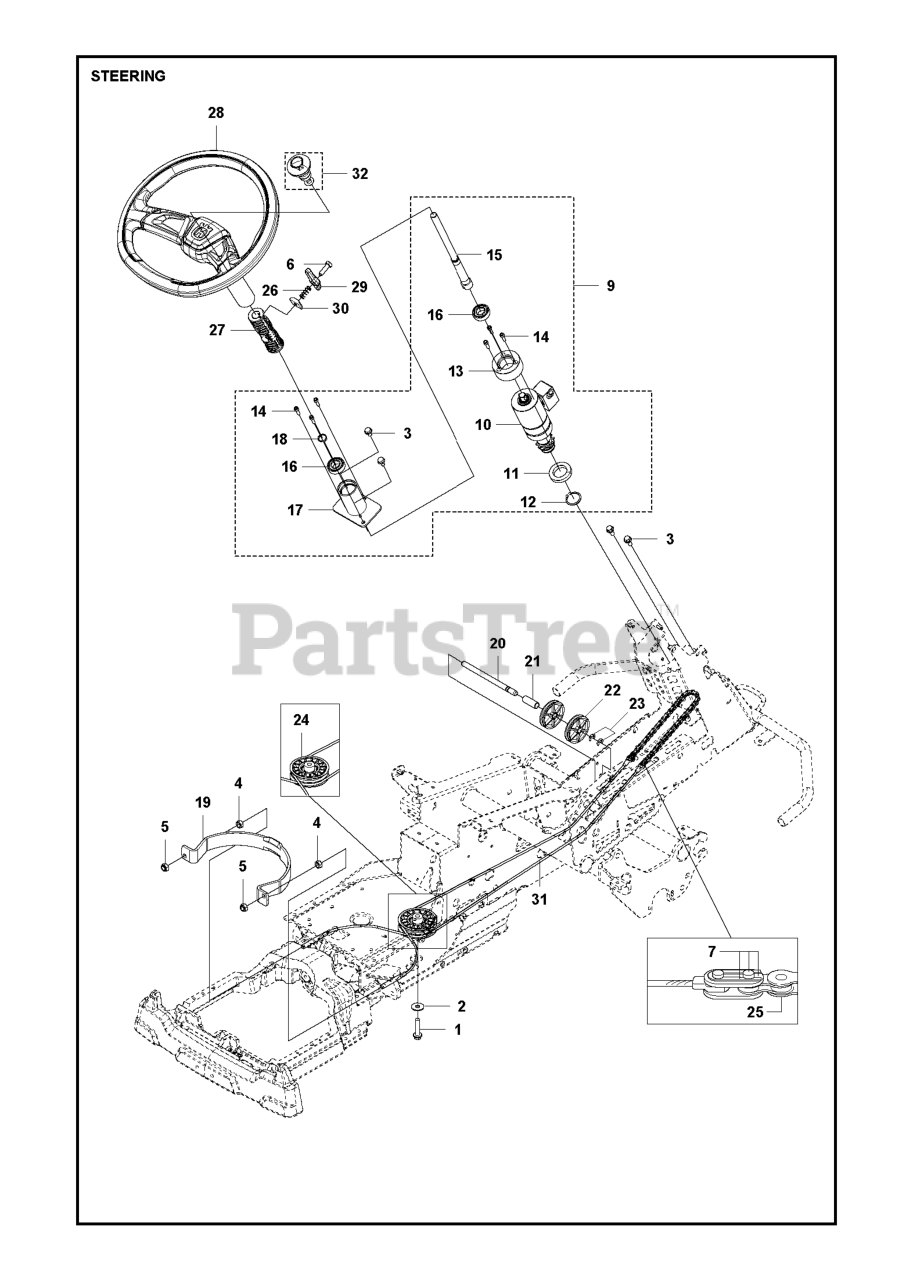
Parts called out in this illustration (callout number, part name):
1	COLLAR SCREW
10	COMFORT STEERING
14	SCREW MC6S 6X20
16	BALL BEARING 6004-2RS1
18	RETAINING RING SGA 20
23	RETAINING RING
26	SPRING STEERING ADJUSTMENT
27	DRIVER STEERING WHEEL
30	FIXING PLATE
